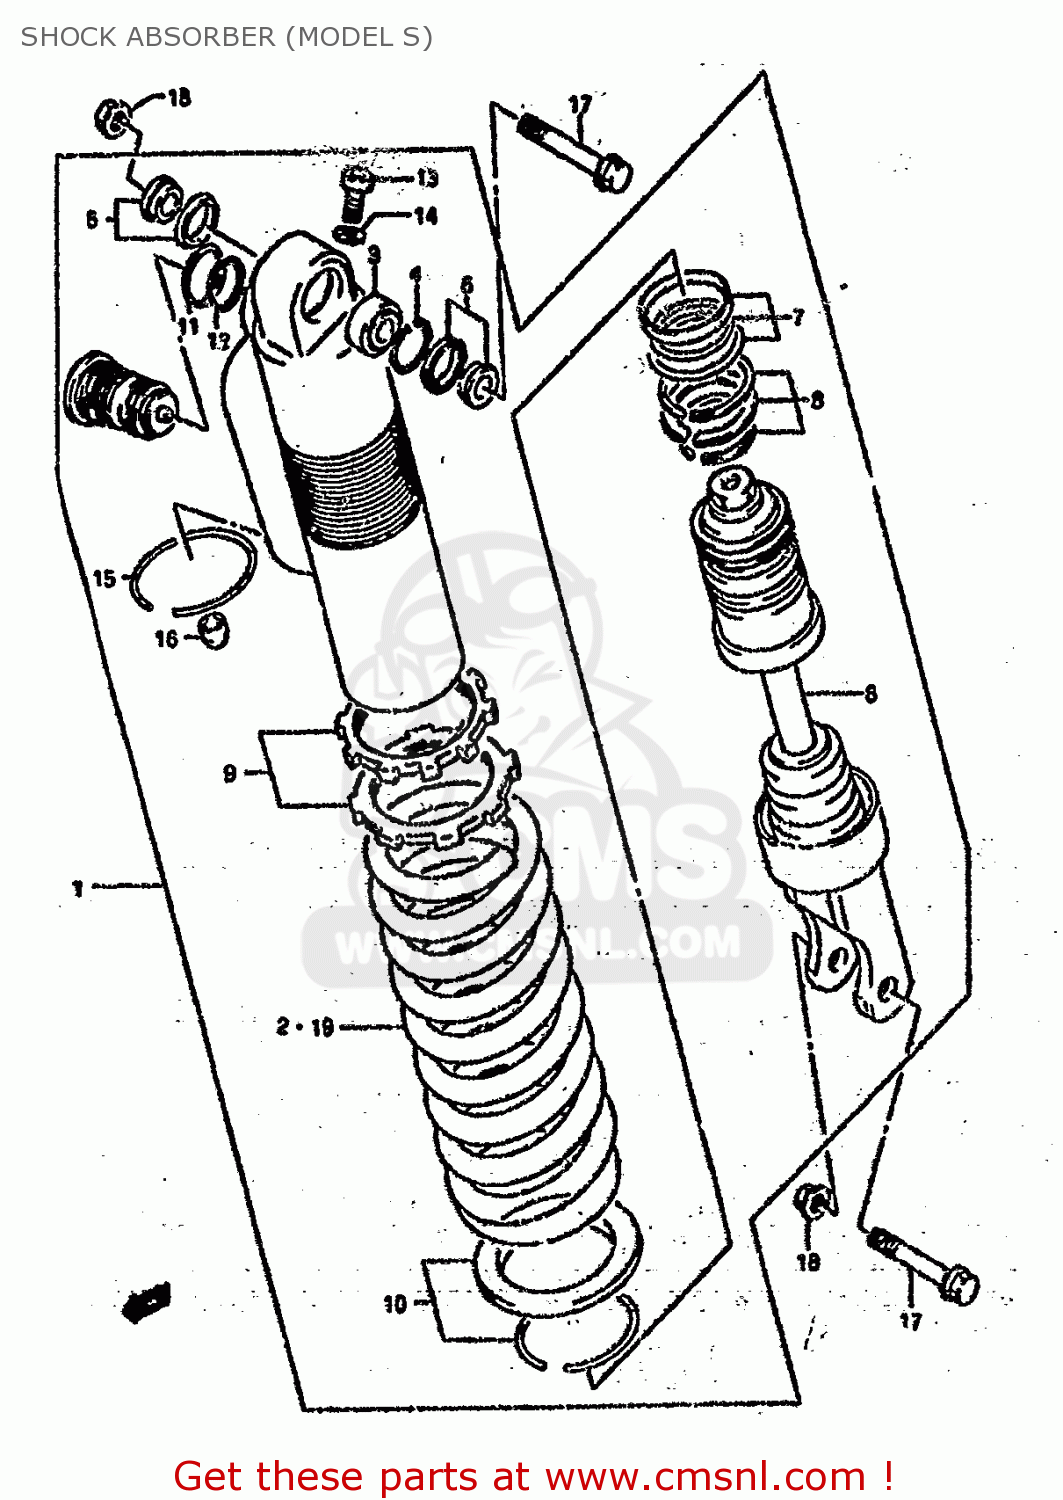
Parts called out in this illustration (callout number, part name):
1	ABSORBER ASSEMBLY,REAR SHOCK
2	SPRING(K:5.2)
3	BEARING,RR CUSHION LEVER RR
4	RING,STOPPER
5	COLLAR SET,RR SHOCK ABSORBER
6	ROD,PISTON
7	O RINR SET
8	RING STOPPER SET,ABSORBER
9	ADJUSTER SET,SHOCK ABSORBER
10	SPRING SEAT SET,SHOCK ABSORBER
11	O RING
12	O RING,CTR BOLT UPR
13	BOLT,REAR SHOCK ABSORBER
14	GASKET,DRAIN,PLUG (NAS)
15	RING,STOPPER
16	CAP
17	BOLT,RR SHOCK ABSORBER
18	NUT
19	SPRING,REAR (K=5.4)
21	CAP
22	BOLT,RR SHOCK ABSORBER
23	NUT
24	SPRING
